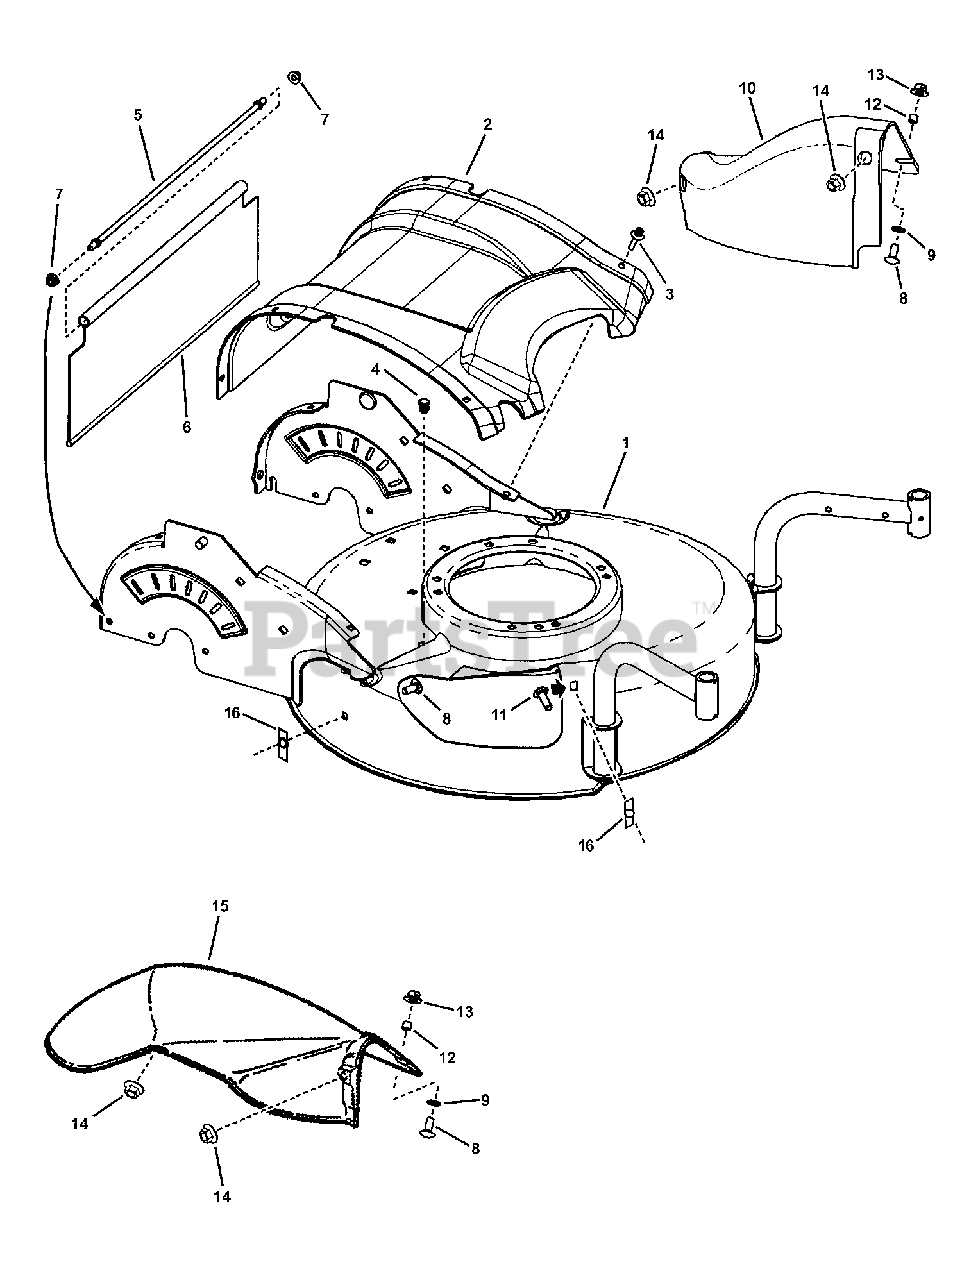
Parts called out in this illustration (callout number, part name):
1	WELDMENT, 21" Deck Swivel Wheel
2	REAR COVER, Belt/Transmission
3	SCREW, 7mm x 1 x .550 AB Point
4	PLUG, Hole (Polyethylene)
5	ROD, Trail Shield
6	SHIELD, Trail
7	NUT, 1/4-20 Hex Flange Lock
8	BOLT, 5/16-18 x 3/4" Short Square Neck Carriage, GR 5
9	BOLT RETAINER, 5/16- Black
10	COVER, 21 Deck Recycling
11	BOLT, 5/16-18 x 1-1/8" Short Square Neck Carriage, GR 5
12	SPACER, .316 x .375 x .300/.310
13	NUT, 5/16-18 Large Flange Hex Center Lock
14	NUT, 5/16-18 Hex Flange Lock
15	CHUTE, 21 Side Discharge
16	NUT, 5/16-18 Speed
